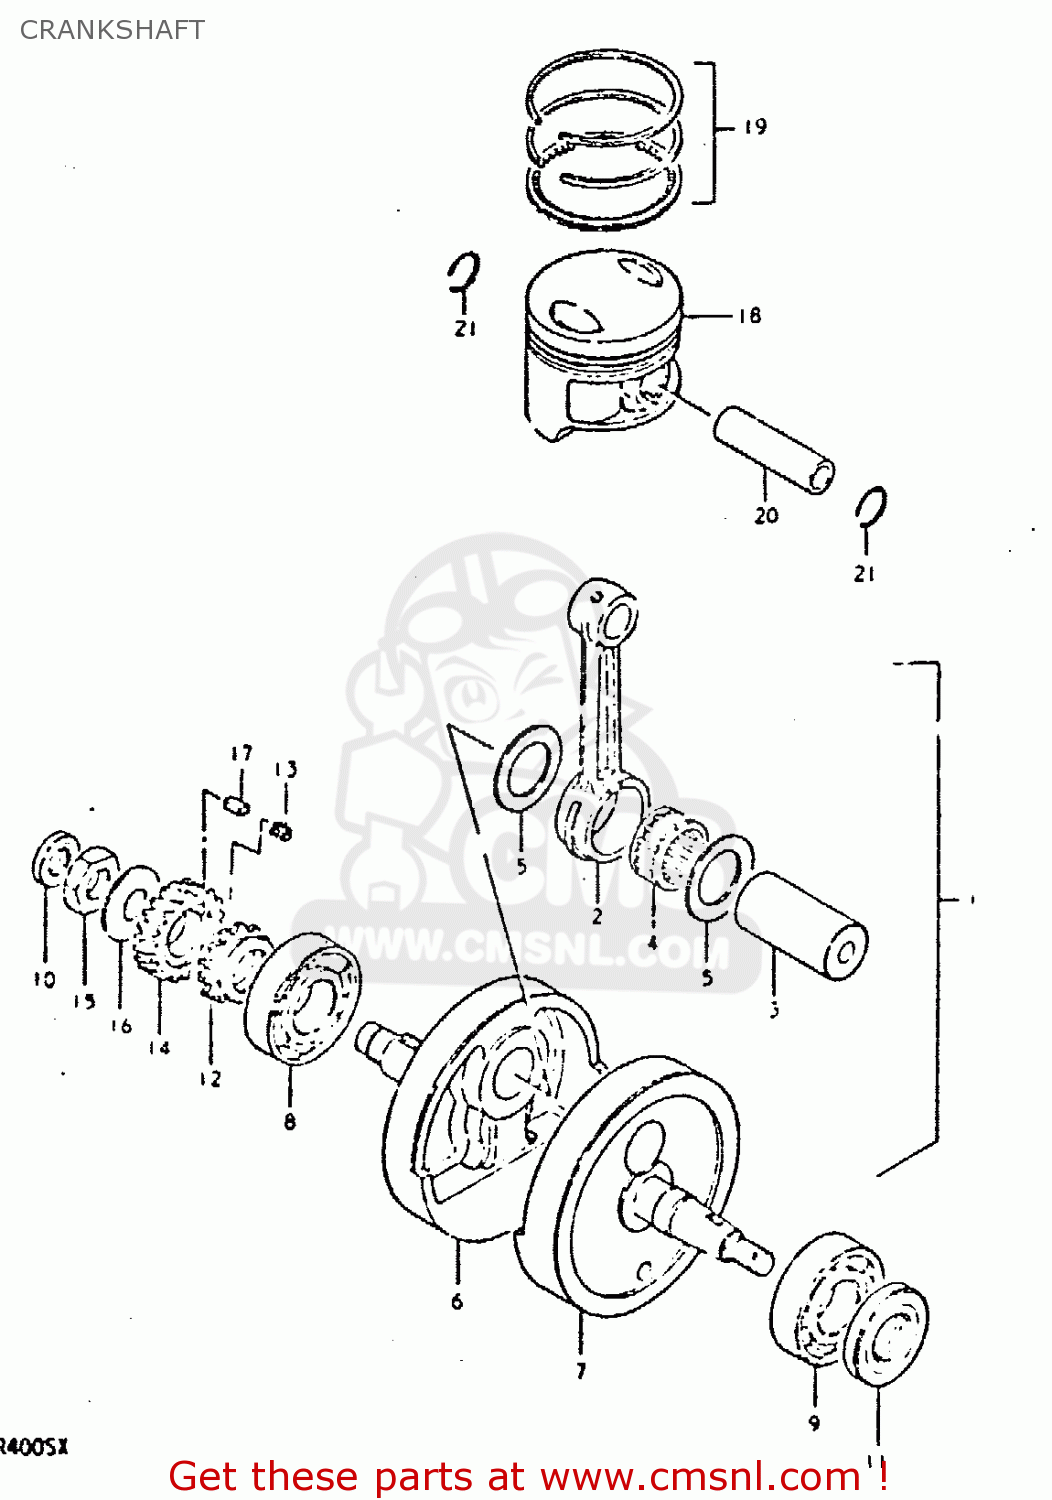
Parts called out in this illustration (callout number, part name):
1	CRANKSHAFT ASSEMBLY
2	ROD,CONNECTING
3	PIN,CRANK
4	BEARING
5	WASHER(34X52X1)
6	CRANKSHAFT
7	CRANKSHAFT,LEFT
8	BALL BEARING 30X72X19
9	BALL BEARING 30X72X19
10	SEAL,OIL(16X30X6)
11	SEAL,OIL(30X58X7)
12	SPROCKET,CAM CHAIN DRIVE
13	KEY,SPROCKET
14	GEAR,PRIMARY DRIVE
15	NUT (20MM)
16	WASHER
17	KEY
18	PISTON
19	RING SET,PISTON
20	PIN,PISTON
21	CIRCLIP
